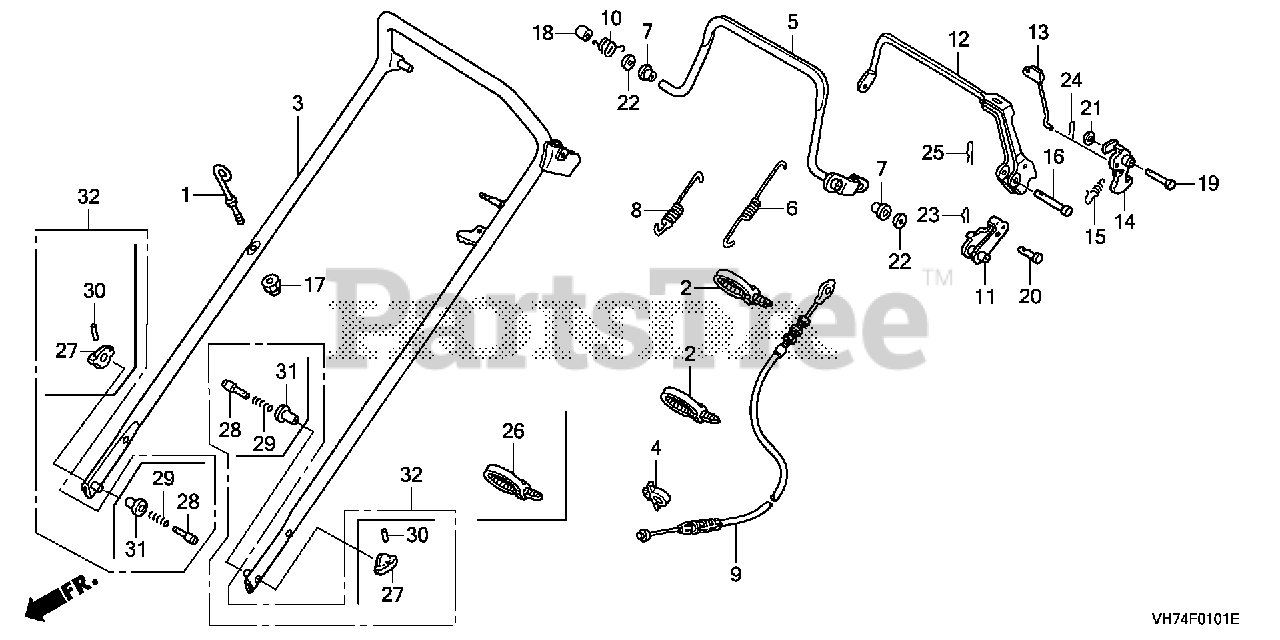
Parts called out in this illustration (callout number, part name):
1	GUIDE, ROPE
2	TIE, CABLE (157.5MM)
3	PIPE, HANDLE *NH105* (MAT BLACK)
5	LEVER, CLUTCH
6	SPRING, CLUTCH
7	BUSH, CLUTCH LEVER
8	SPRING, CLUTCH LEVER RETURN
9	CABLE, ROTO-STOP
10	SPRING, R. STOP RETURN
11	ARM, ROTO-STOP CABLE
12	LEVER, ROTO-STOP (FOR U.S.A.)(COO)
13	ROD, RATCHET PUSH
14	LEVER, LOCK
15	SPRING, RATCHET RETURN
16	PIN, CLUTCH LEVER
17	NUT, NYLON LOCK (6MM)
18	COLLAR (8X11X13.5)
19	PIN, LOCK LEVER HINGE (6X30)
20	PIN, CABLE JOINT
21	WASHER, PLAIN (6MM)
22	WASHER, PLAIN (8MM)
23	PIN, SPLIT (1.6X12)
24	PIN, LOCK (6MM)
25	PIN, LOCK (8MM)
26	TIE, CABLE (157.5MM)
27	GRIP, HANDLE JOINT *NH164* (GRIP GRAY)
28	PIN (8MM)
29	SPRING, HANDLE ADJUSTING
30	PIN, COILED (2X12)
31	COLLAR, HANDLE HEIGHT ADJUSTING
